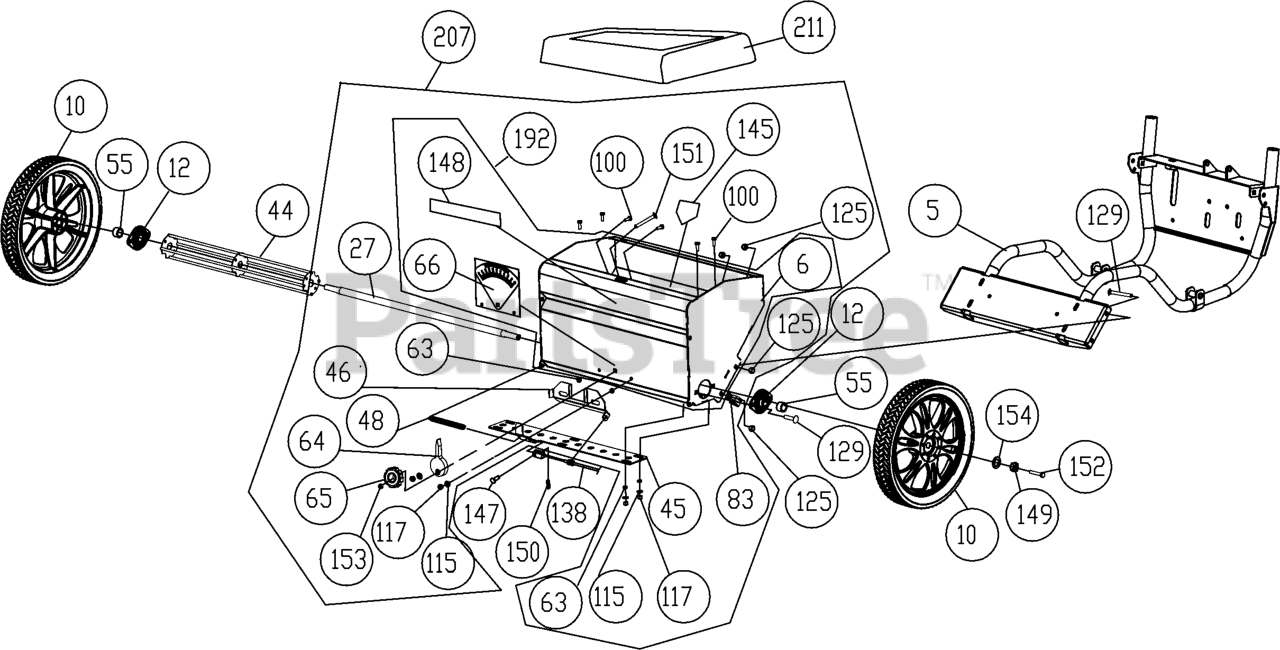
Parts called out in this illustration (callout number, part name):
5	FRAME SUPPORT OS900SP WA
6	SEED BOX WA
10	WHEEL 14" ASSY FRONT
12	BEARING & FLANGETTE ASSY .75"
27	AXLE SEED BOX
44	WHEEL PADDLE SEED WA
45	SEE: 351620
46	BRACKET CONTROL SEED RATE
48	SPRING EXTENSION .500"X5.00"
55	SPACER SEED BOX AXLE
63	SPACER SEED PLATE
64	CAM SEED RATE
65	KNOB 5/16"-18 X 5/8" FLUTED
66	LABEL SEED FLOW RATE
83	CLAMP ROUTING FUEL LINE
100	SCREWCAP 1/4"-20X3/4" HCS ZP
115	WASHER 1/4"SAE9/32"X5/8"X1/16"
117	NUT LOCK 1/4"-20 HEX Z/P
125	NUT FLANGE 5/16"-18 ZP
129	BOLT CARRIAGE 5/16"-18 X 3/4" ZP
138	CABLE CLUTCH SEEDING CONTROL
145	LABEL WARNING OPEI
147	PIN CLEVIS 1/4" X .61
148	LABEL BADGING
149	WASHER LOCK 5/16" TWISTED TOOTH HEAVY
150	PIN CLIP HITCH 0.051 X 3/4"
151	BOLT CARRIAGE 5/16"-18 X 1 1/4" ZP
152	SCREWCAP 5/16"-18X3/4" HCS ZP
153	NUT LOCK 5/16"-18 LT WT TH ZP
154	WASHER FLAT FENDER 5/16
192	SEED BOX W/LABELS
207	KIT SEED BOX OSSP SERVICE
211	SEED BOX BONNET
